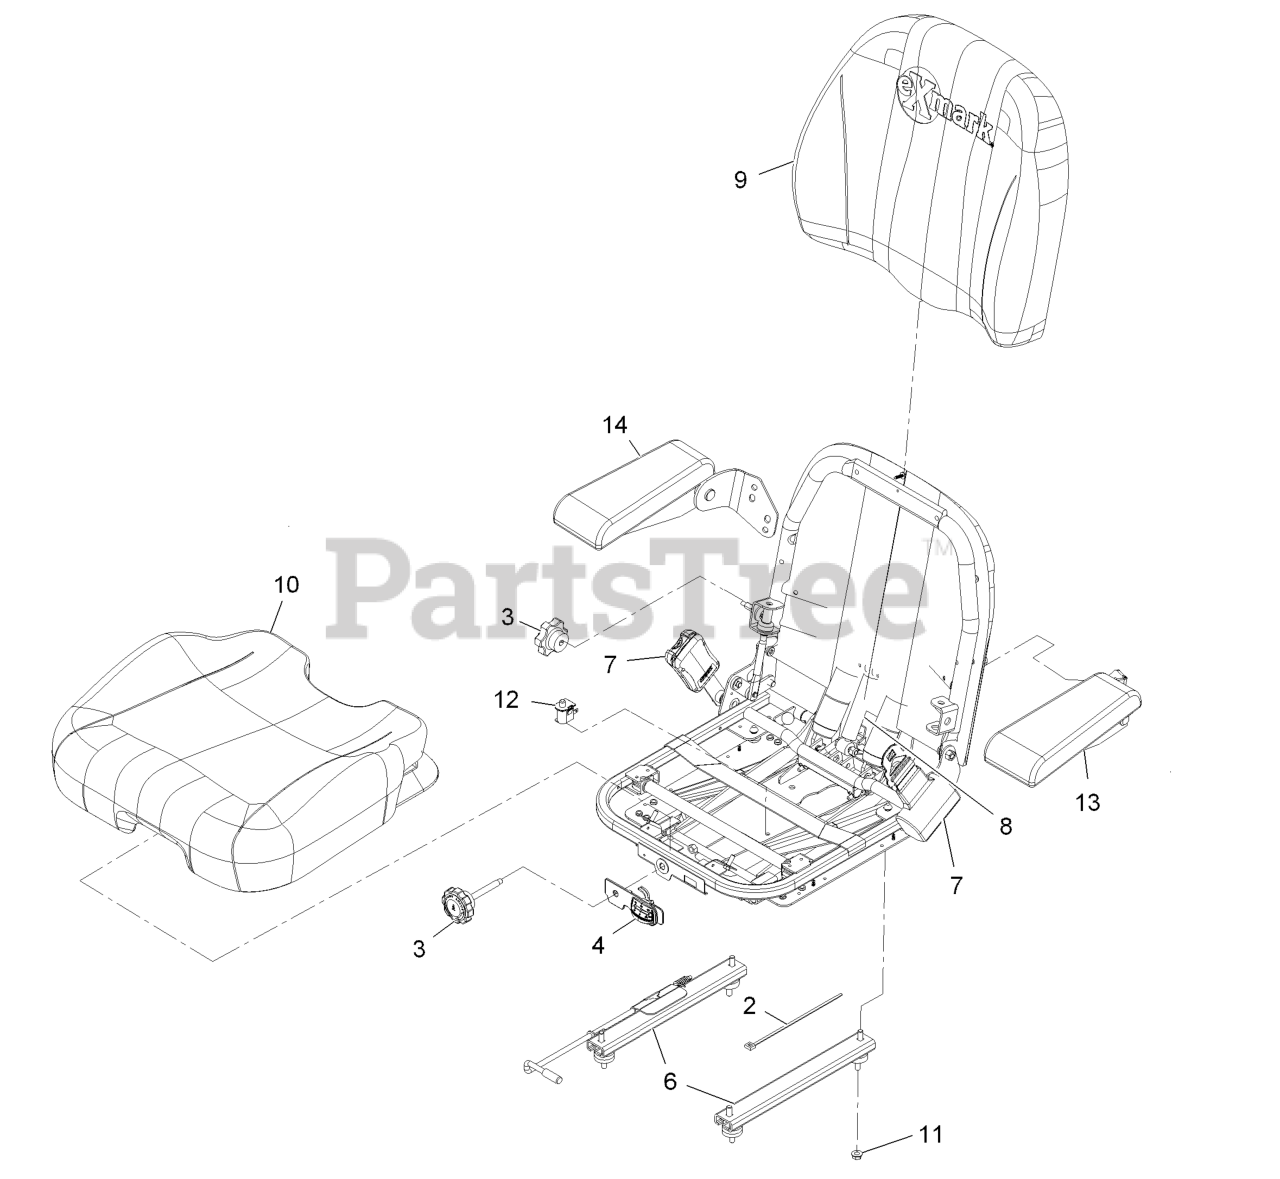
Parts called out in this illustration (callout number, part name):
2	TIE-PLASTIC
3	KNOB KIT
4	WEIGHT INDICATOR KIT
6	SEAT TRACK KIT
7	SEAT BELT KIT (SHORT)
8	SHOCK ABSORBER KIT
9	KIT,BACK CUSHION AND COVE
10	KIT,BOTTOM CUSHION AND CO
12	SWITCH-BAIL
13	ARM REST ASM,SUSP.SEAT LH
14	ARM REST ASM,SUSP.SEAT RH
